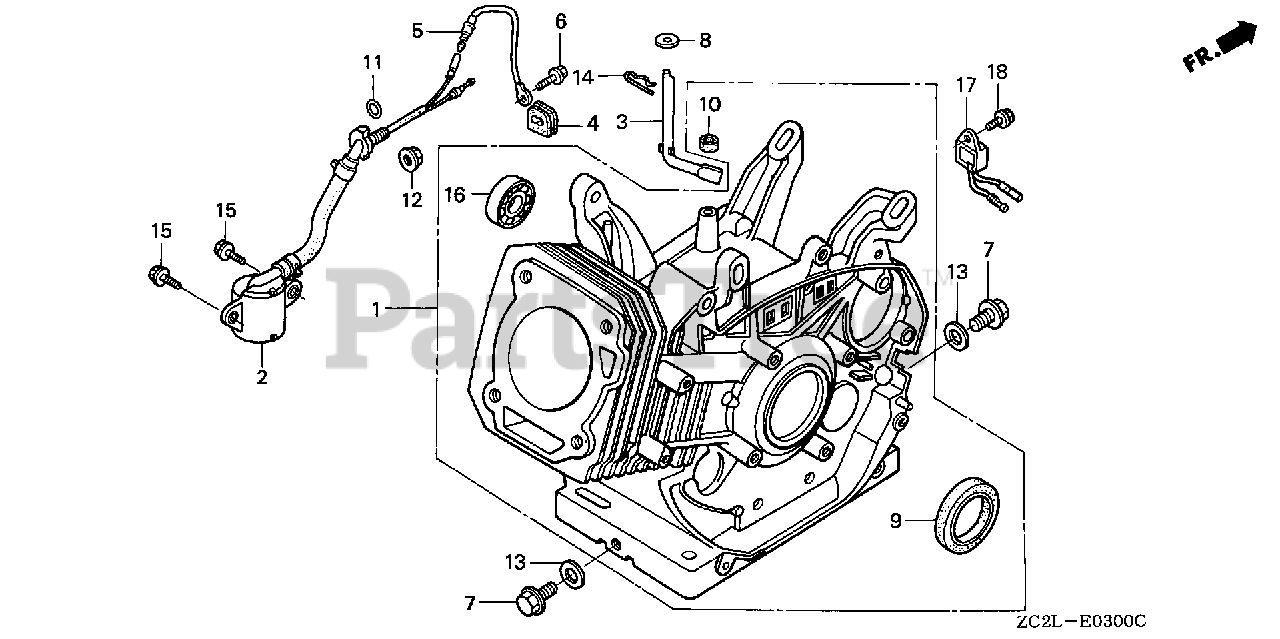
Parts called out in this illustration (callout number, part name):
1	CYLINDER ASSY. (ALERT)
2	SWITCH ASSY., OIL LEVEL
3	SHAFT, GOVERNOR ARM
4	GROMMET, WIRE
7	BOLT, DRAIN PLUG (12X15)
8	WASHER (8.2X17X0.8)
9	OIL SEAL (35X52X8)
10	OIL SEAL (8X14X5)
11	O-RING (14MM) (ARAI)
11	O-RING (14MM) (NOK)
12	NUT, FLANGE (10MM)
13	WASHER, DRAIN PLUG (12MM)
14	PIN, LOCK (10MM)
15	BOLT, FLANGE (6X12)
16	BEARING, RADIAL BALL (6202)
17	ALERT UNIT, OIL
18	BOLT, FLANGE (6X12) (CT200)
